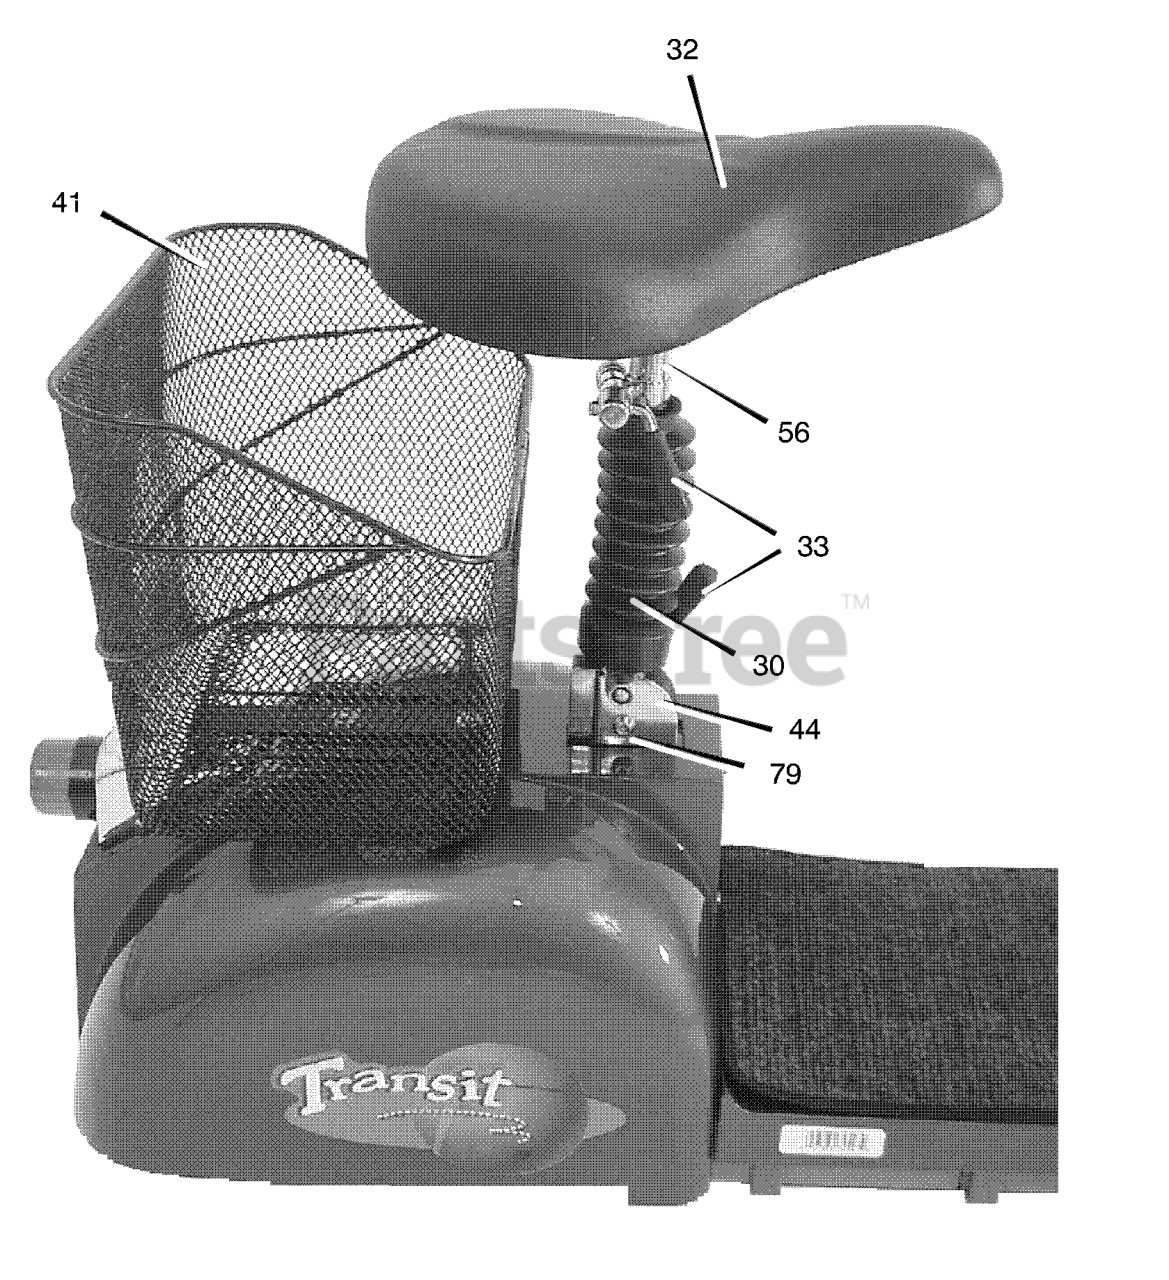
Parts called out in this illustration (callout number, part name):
30	Bellows, Seat Support
33	Lever Assembly, Quick Release
41	Basket-Black
44	Bracket, Seat Post Mount
56	Seat Support Ass'y-Telescoping
79	Screw, Pivot
